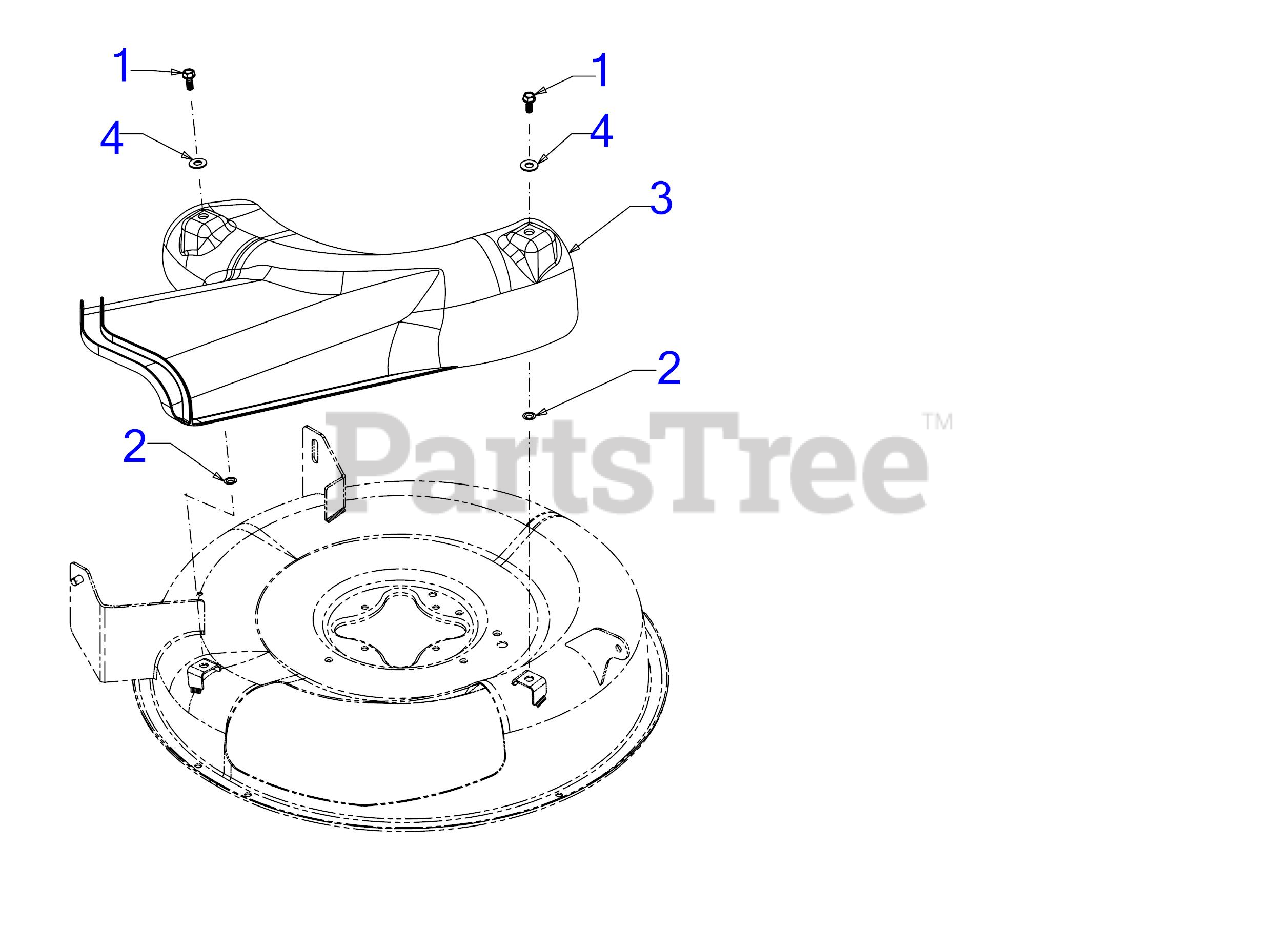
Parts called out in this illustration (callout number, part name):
1	HEX SCREW 5/16-18 x .750
2	PUSH NUT
3	DISCHARGE CHUTE
4	FLAT WASHER
